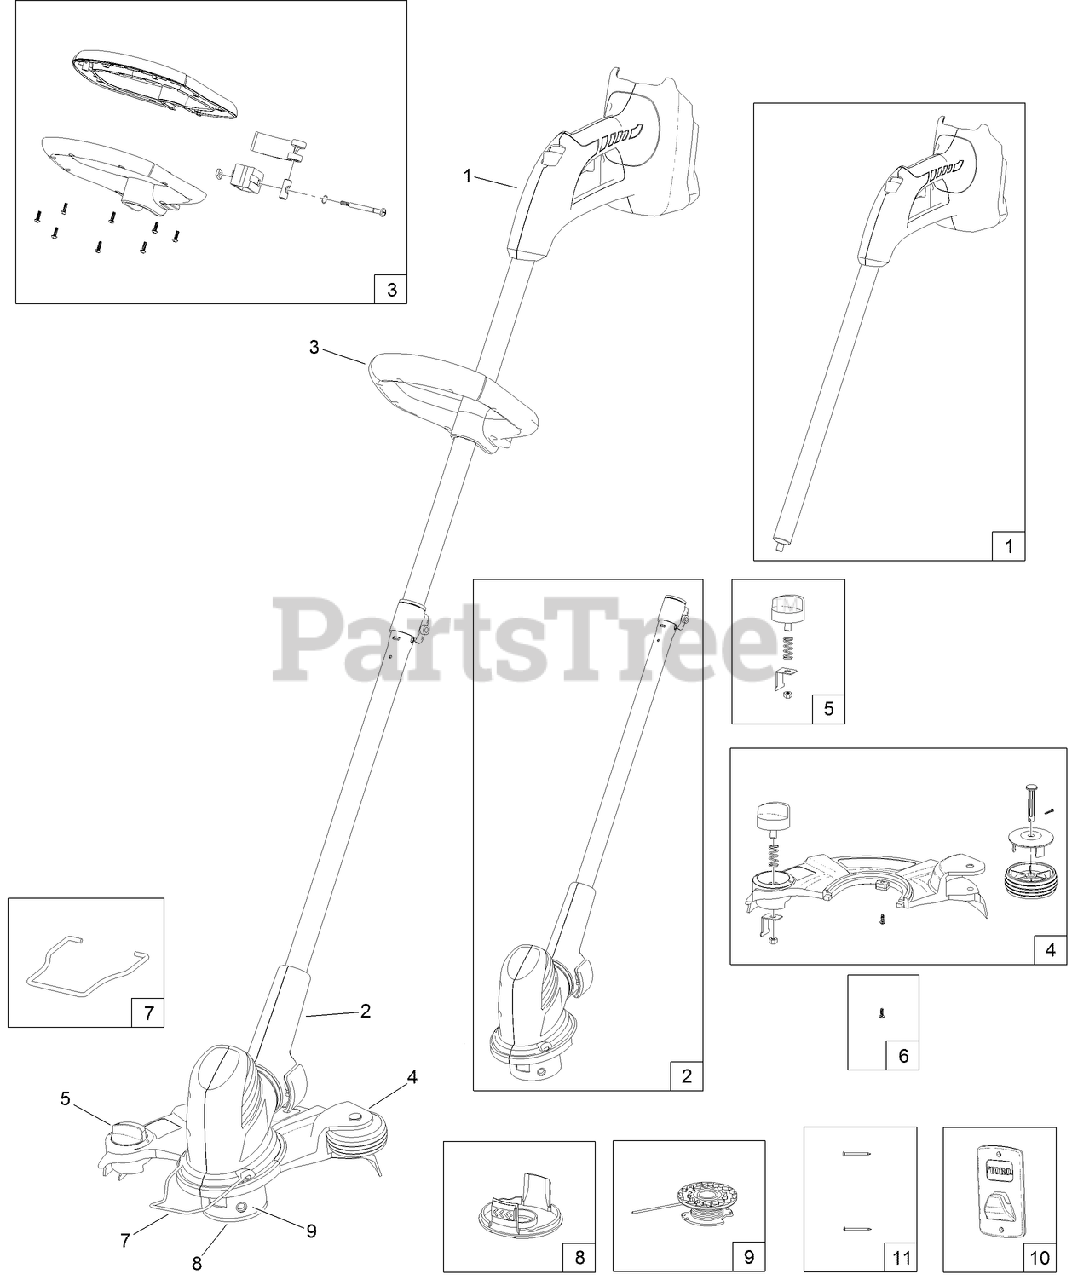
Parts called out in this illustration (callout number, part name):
1	HANDLE-UPPER
2	HOUSING-MOTOR, LOWER
3	ASSIST HANDLE ASM
4	SHIELD ASM
5	KNOB-SAVER, POWER
7	CLIP-GUIDE, EDGER
8	CAP-RETAINER, SPOOL
9	SPOOL-REPLACEMENT
10	BRACKET-MOUNT, WALL
11	SCREW (Wall Mount Bracket)
